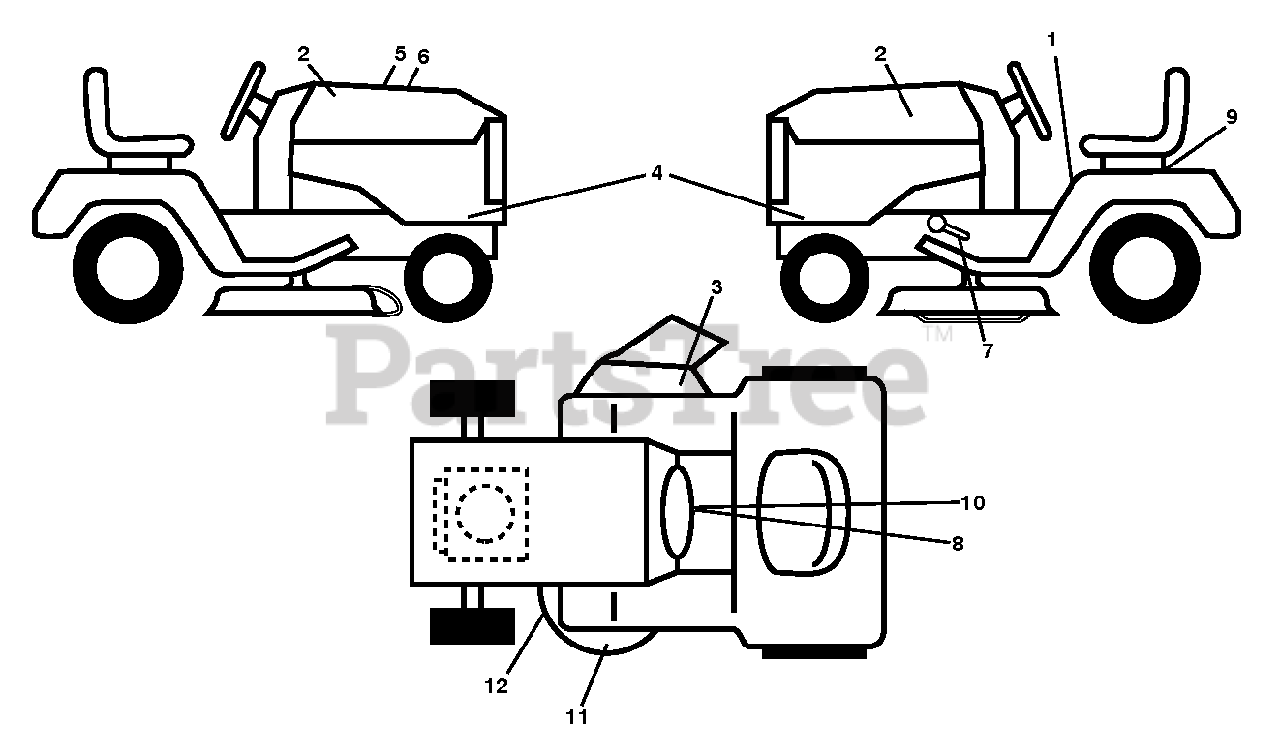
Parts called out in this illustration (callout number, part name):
1	DECAL.FENDER.WARNING
2	RP.DECAL.BADGE.170MM.TEXTLOGO
3	DECAL.WARN.KEEP.HAND.AWAY
4	DECAL.SDPNL.GT2.YT46LS.SET
5	DECAL.WARNING.CUST.RESP.E85.
6	DECAL.RPL.KW.FR651.TLW.46.K46L
7	DECAL.PEDAL.HUSQ.CROWN
8	LABEL.EMISS.CALIF.HUSQVARNA
9	DECAL BTRY SYMBOLS
10	DECAL, WARNING SPARK ARRESTOR
11	TRACTOR.APDECK.POP.HUSQVARNA
12	DECAL V BELT SCHEMATIC
